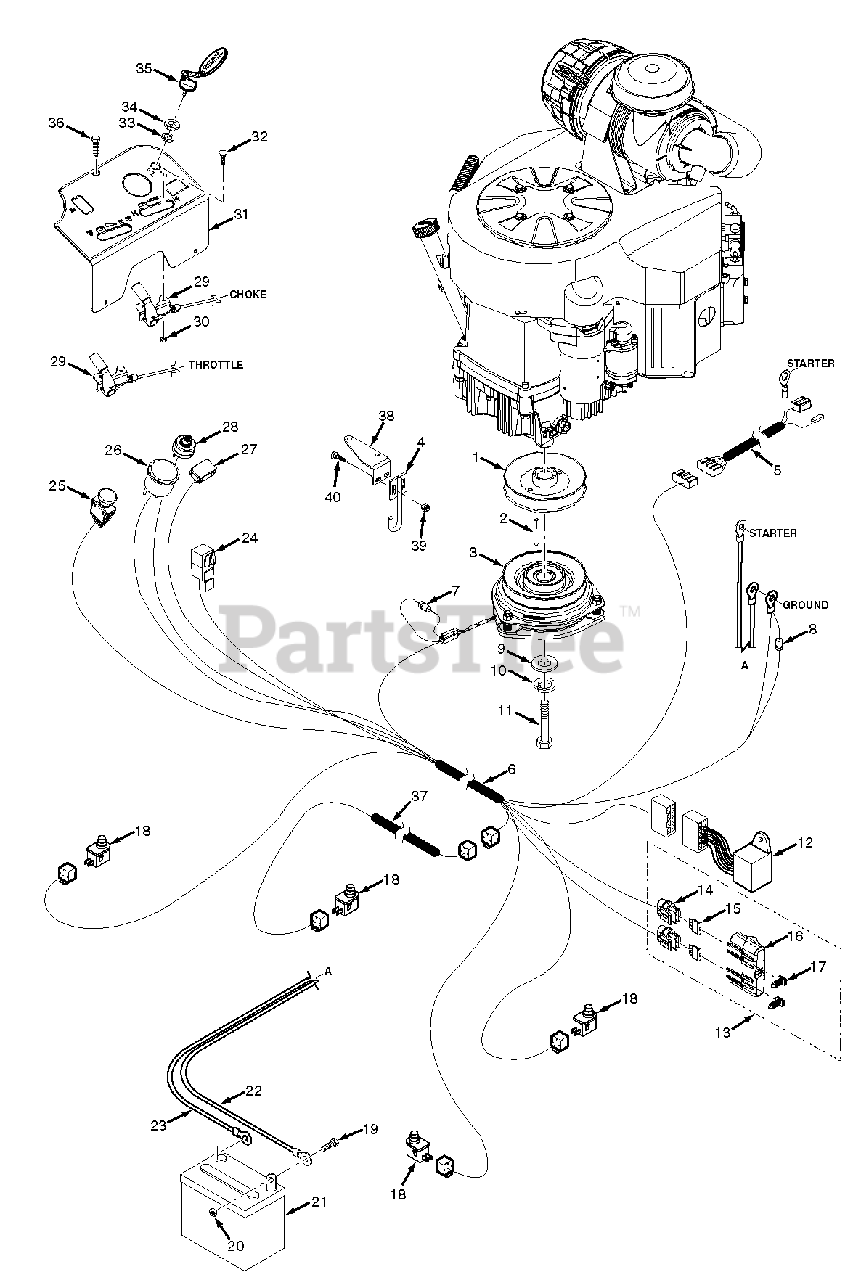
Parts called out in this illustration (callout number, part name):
1	Pulley, 5.80 Dia. - 1.125 Bore
2	Key, 1/4 x 1/4 x 3-1/4"
3	Electric Clutch w/Tag (GT-3.5)
3	Electric Clutch w/Tag (GT-5) - 72V
4	Weldment, Anti-Rotation
5	Wire Harness Adapter, Kawasaki
5	Wire Harness Adapter, Briggs & Stratton
5	Wire Harness Adapter, Kohler
6	Wire Harness, SCZ
7	Diode, 600V - 6A
8	Diode
9	Flatwasher, 7/16-.469 x 1.75 x .25
10	Lockwasher, 7/16" Spring
11	Bolt, Hex Head 7/16-20 x 2-1/4" w/Patch (Kawasaki)
11	Bolt, Hex Head (Briggs & Stratton)
12	Electric Module
13	Double Fuse Assembky
14	Fuse Holder
15	Fuse, 20 Amp
16	Cover, Sealed Double
17	Clip, Wire
18	Switch, N.O.
19	Bolt, Hex Head 1/4-20 x 1/2"
20	Nut, 1/4-20
21	Battery
22	Battery Cable, 27" Black
22	Battery Cable, 18" Black (Kohler)
23	Battery Cable, 25" Red
24	Relay
25	Switch, PTO - 10 Amp
26	Ammeter
27	Hourmeter
28	Keyswitch w/Hardware
29	Control Cable (Kawasaki, Kohler Choke Cable)
29	Control Cable (Briggs & Stratton)
29	Control Cable (Kohler Throttle Cable)
30	Nut, Elastic Stop #10-24
31	Instrument Panel w/Decal
32	Bolt, Carriage #10-24 x 1/2"
33	Lockwasher, 5/8" Internal
34	Nut, Hex 5/8-32
35	Key, Ignition
35	Key Assembly w/Fob
36	Bolt, Hex Head 1/4-20 x 1/2" Serrated Flange
37	Wire Harness, Operator Platform -SCZ
38	Bracket, Anti-Rotation
39	Nut, FLF HH Elastic Stop 5/16-18
40	Bolt, Carriage 5/16-18 x 1"
